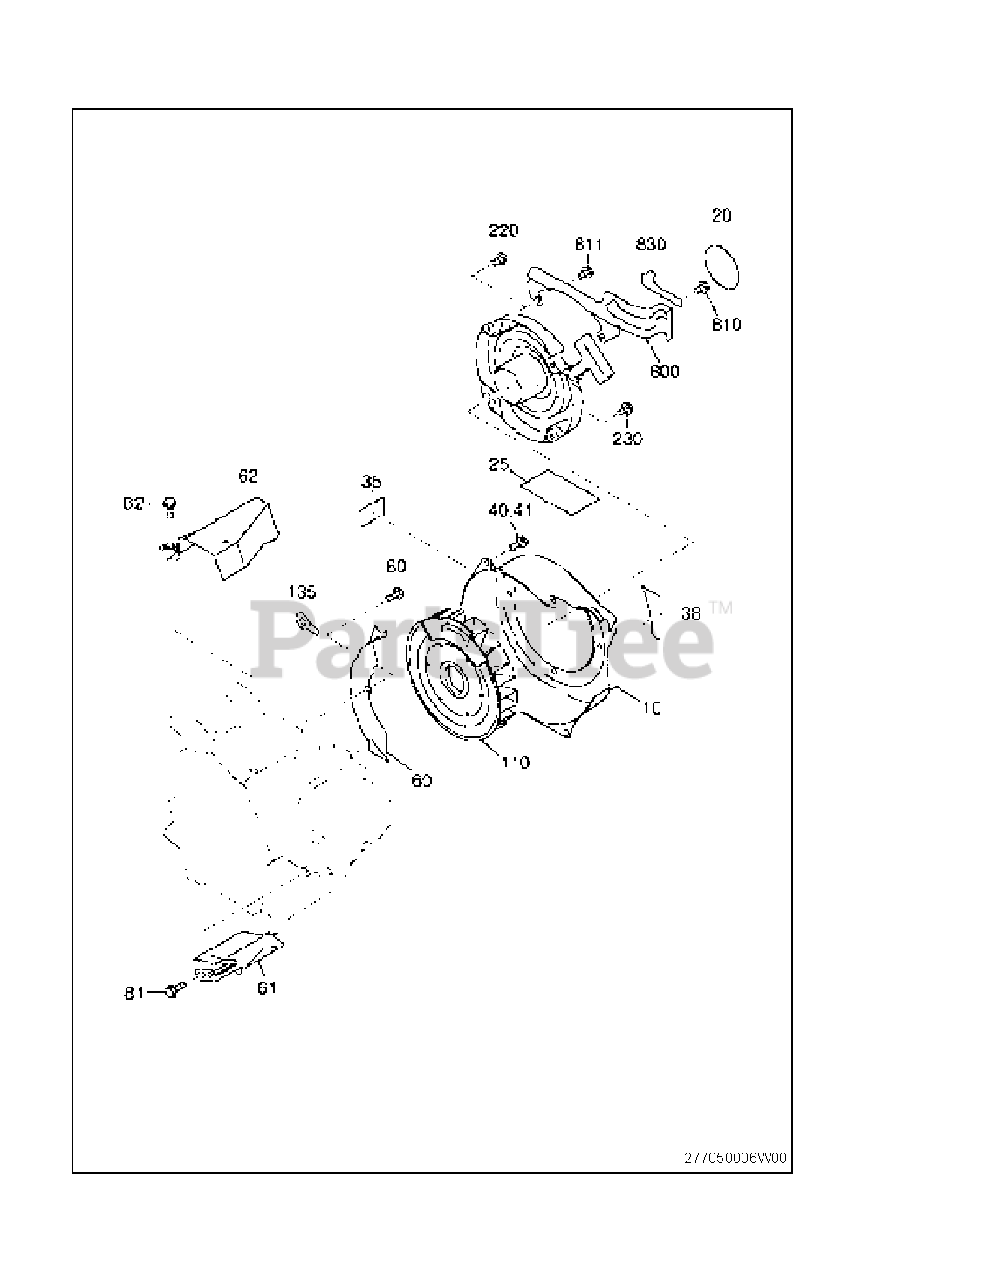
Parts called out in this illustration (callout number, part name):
10	BLOWER HOUSING CP
20	LABEL(TRADE MARK)
38	LABEL(FUEL COCK)
60	BAFFLE 1(CASE) CP
61	BAFFLE 2(HEAD)
110	COOLING BLOWER
